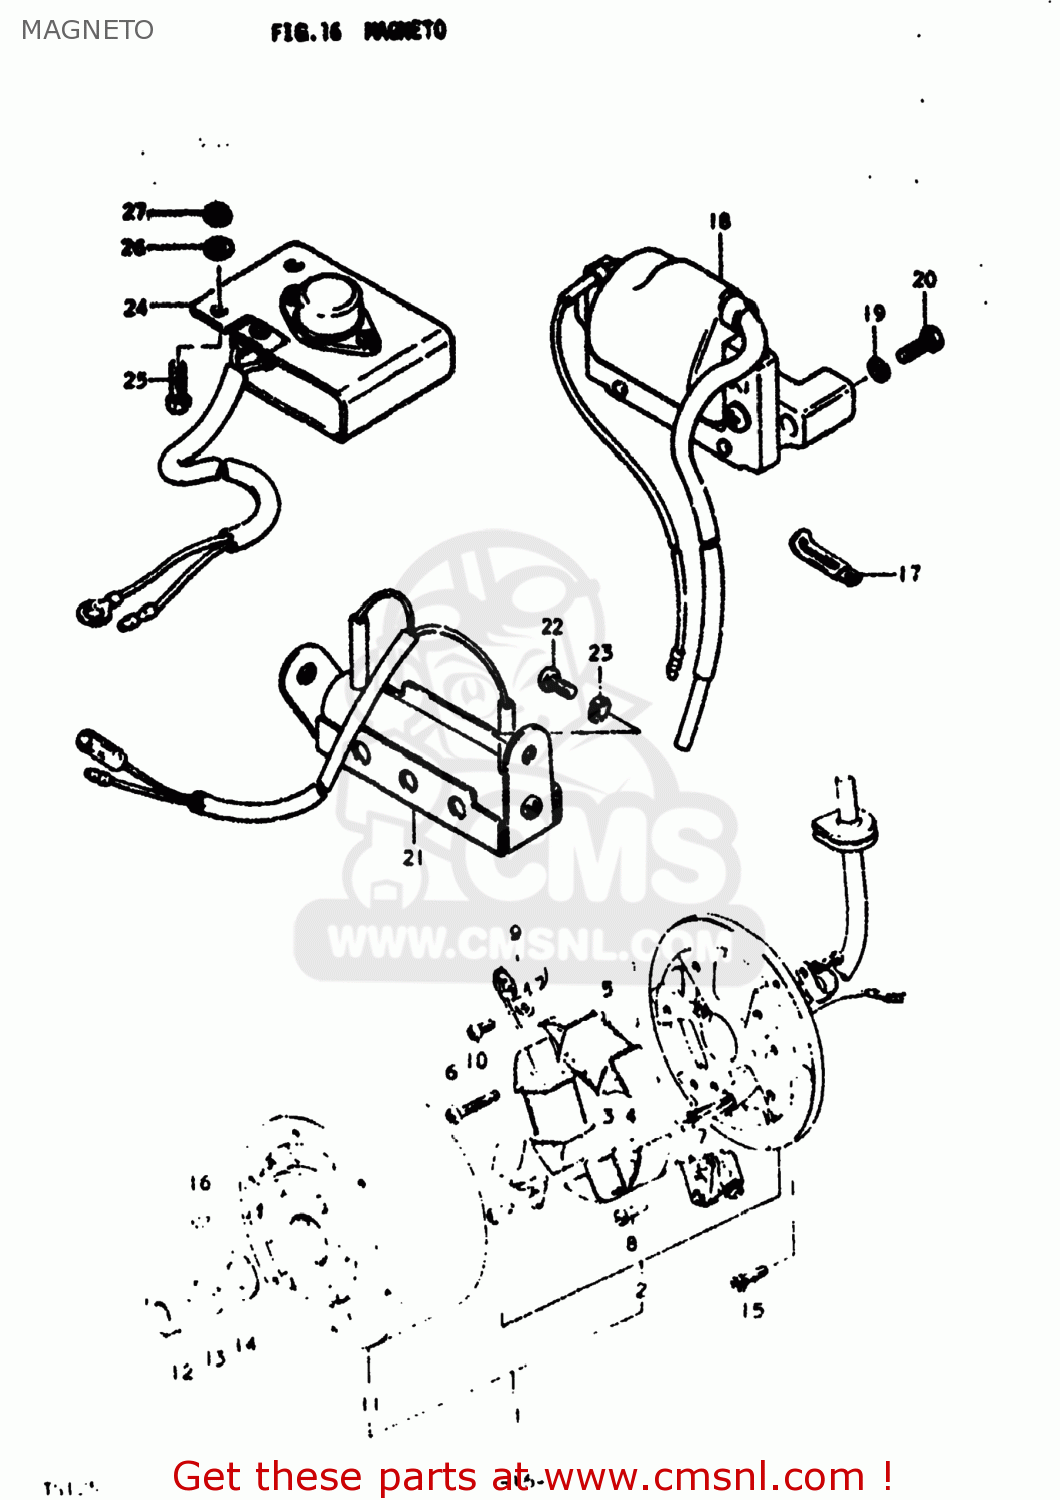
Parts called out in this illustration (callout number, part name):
1	MAGNETO ASSEMBLY
2	STATOR ASSEMBLY
3	COIL,LIGHTING
4	COIL,LIGHTING
5	COIL,PRIMARY
6	SCREW
7	POINT ASSEMBLY,CONTACT
8	.SCREW
9	CONDENSER
10	SCREW
11	ROTOR ASSEMBLY
12	NUT (10MM)
13	LOCK WASHER
14	WASHER
15	SCREW
16	KEY
17	CLAMP L:35
18	COIL ASSEMBLY,IGNITION
19	LOCK WASHER
20	BOLT
21	MAGNETO RESISTOR
22	SCREW
23	LOCK WASHER
24	REGULATOR ASSEMBLY
25	SCREW 6X12
26	WASHER
27	NUT
